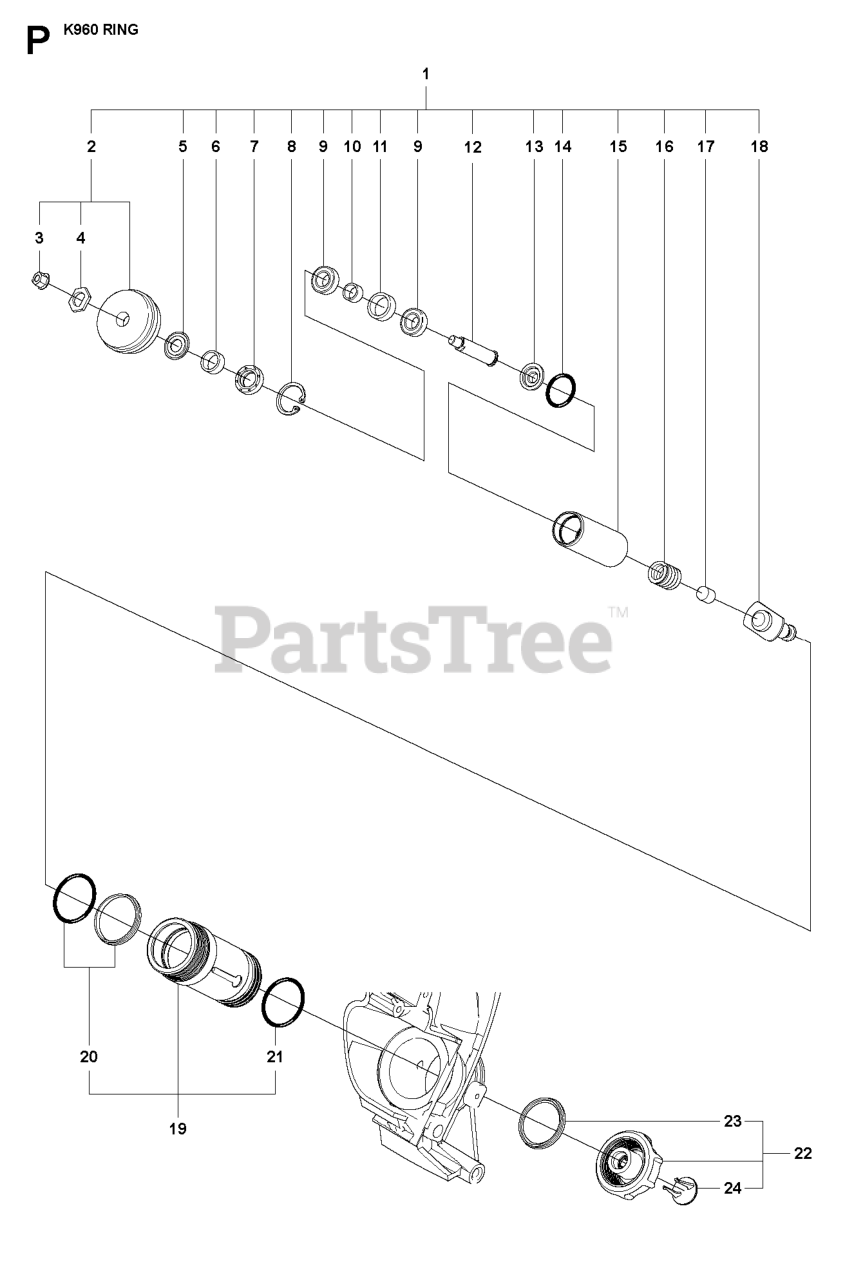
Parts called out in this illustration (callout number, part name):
2	GUIDE ROLLER
3	NUT W/ WASHER
5	DUST COVER
8	RETAINING RING SGH 28
9	BEARING
19	SLEEVE COMPLETE
